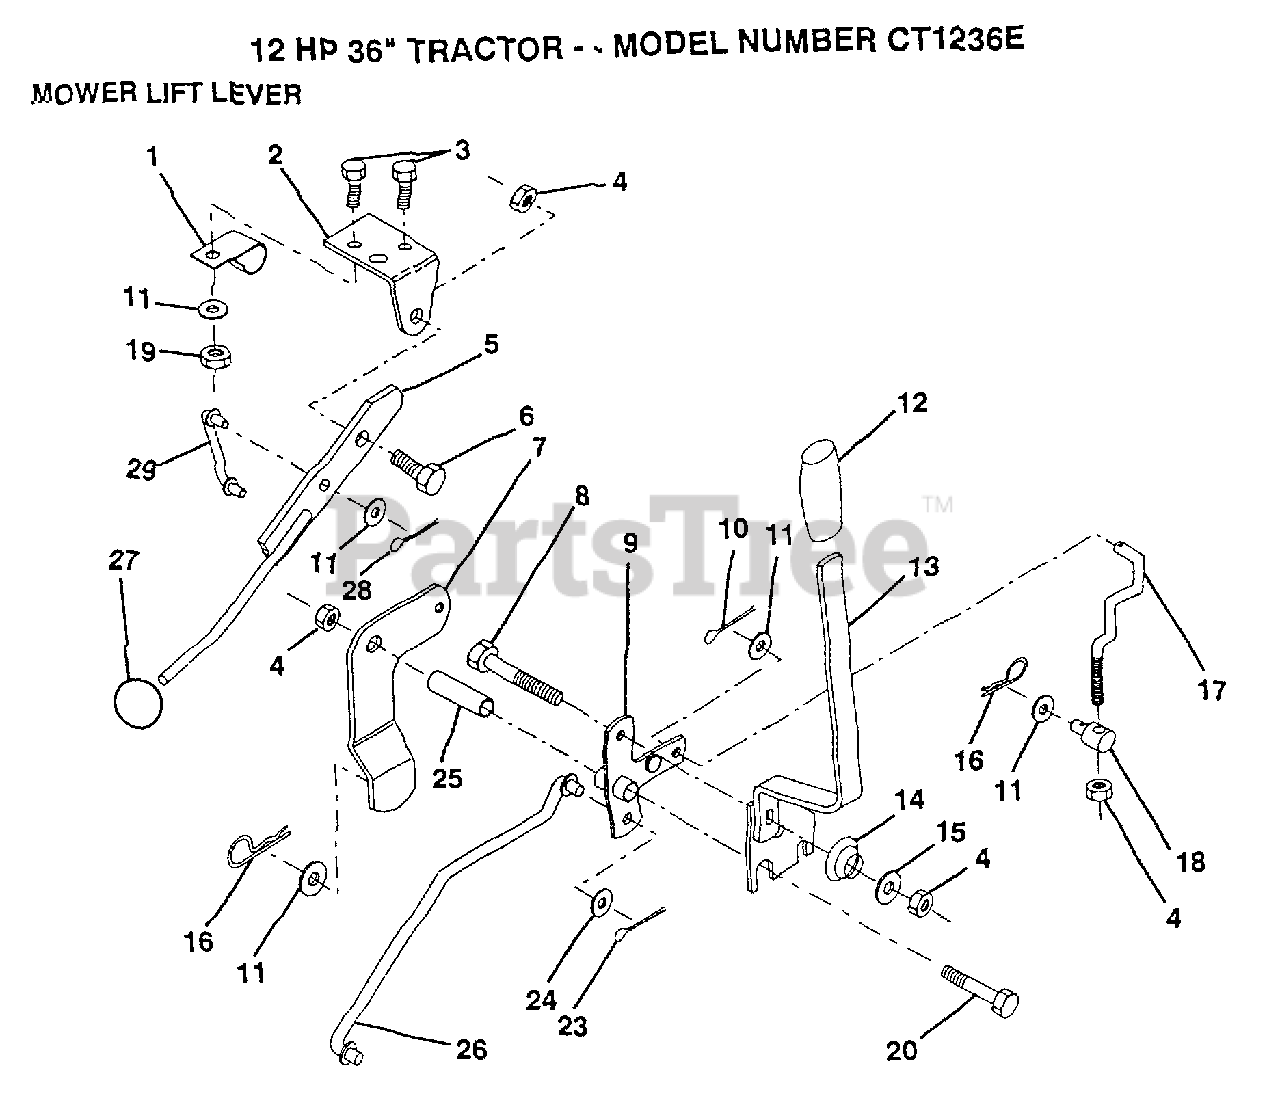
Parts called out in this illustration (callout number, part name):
1	"CLIP,INSULATOR"
2	BRKT CLUTCH
3	BOLT
5	CLUTCH LEVER AS
6	"BOLT, SHOULDER LT"
7	MWR CLUTCH ARM AS
8	BOLT
9	"BELLCRANK,LIFT"
10	COTTER PIN
11	WASHER
12	GRIP HANDLE
13	"HDLE,LIFT T"
14	SPRING COMPRESSIO
15	WASHER T
16	SPRING.RETAINER
17	"LINK,LIFT FRT"
18	TRUNION
20	BOLT
23	PIN COTTER 1/8
25	TUBE SPACER
26	"ROD,MOWER LIFT "
27	KNOB
29	CLUTCH LINK
